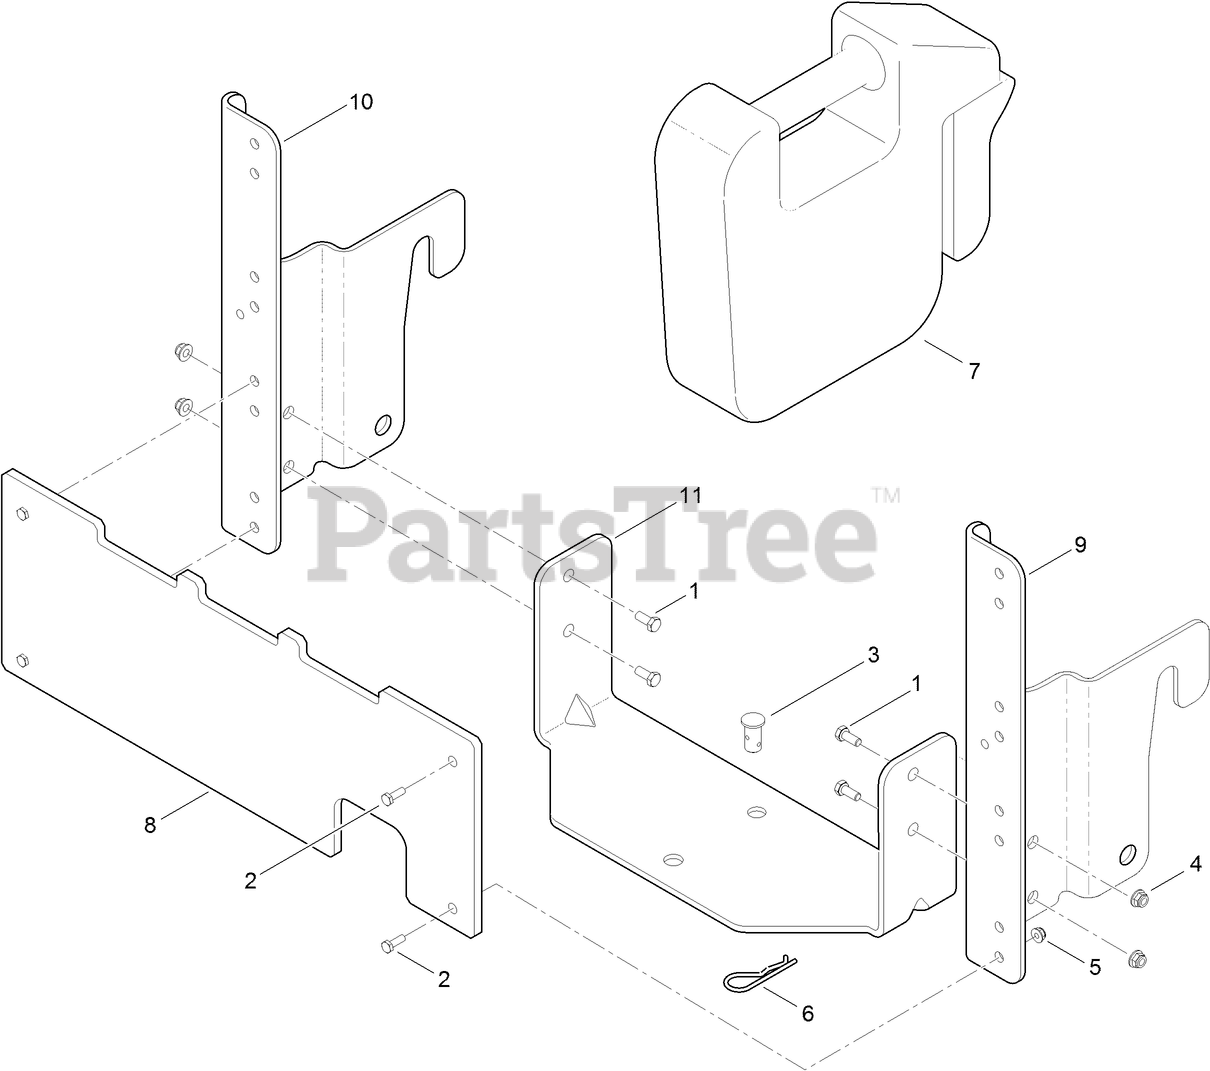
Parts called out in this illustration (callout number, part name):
1	SCREW-HH
2	SCREW-HH
3	PIN-CLEVIS
4	NUT-LOCK, FLANGE
5	NUT-LOCK, FLANGE
6	CLIP-HAIRPIN
7	WEIGHT-SUITCASE
8	PLATE-WEIGHT, REAR
9	BRACKET-CATCHER, RH
10	BRACKET-CATCHER, LH
11	BRACKET-CROSS, SUPPORT
